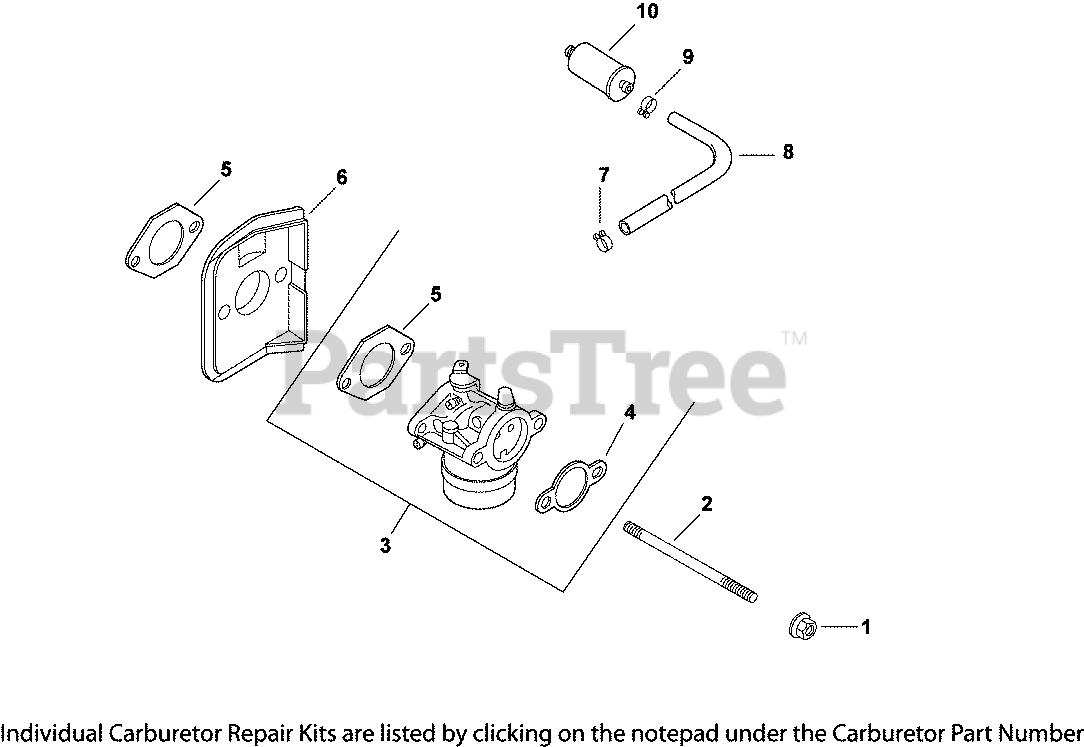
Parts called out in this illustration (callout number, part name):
1	NUT, FLG M6X1.0
2	STUD,M6X1.0X116
3	KIT, CARB W/GASKETS - USE 12 853 177-S
4	GASKET, AIR CLEANER BASE
5	GASKET, CARBURETOR
6	DEFLECTOR, HEAT
7	CLAMP, HOSE (KM)-USE 25 237 31-S
8	HOSE,LW PERM.FUEL 24.00"-USE 25 111 81-S
9	CLAMP, BAND SPRING HOSE-(#2523737S)
10	FILTR,FUEL 75 MICRON (GRAVTY FEED)
